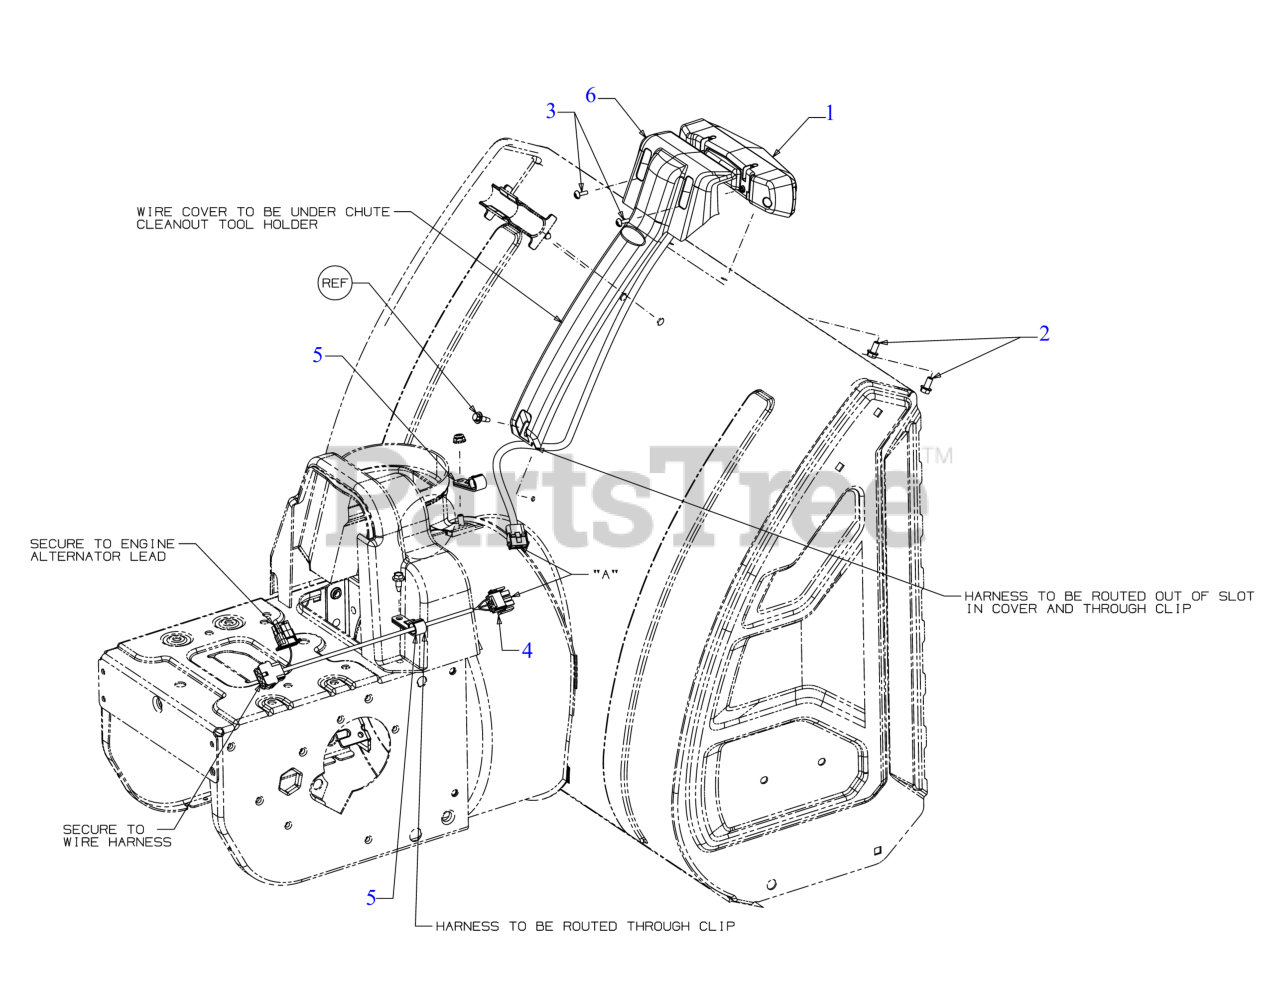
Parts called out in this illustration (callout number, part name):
1	LED LIGHT BAR HEADLIGHT ASSEMBLY
2	HEX SCREW 1/4-15 x .50
3	SCREW 8/16X.500
4	LIGHT BAR HARNESS
5	HEADLIGHT HARNESS CLAMP
6	LED LIGHT BAR COVER
